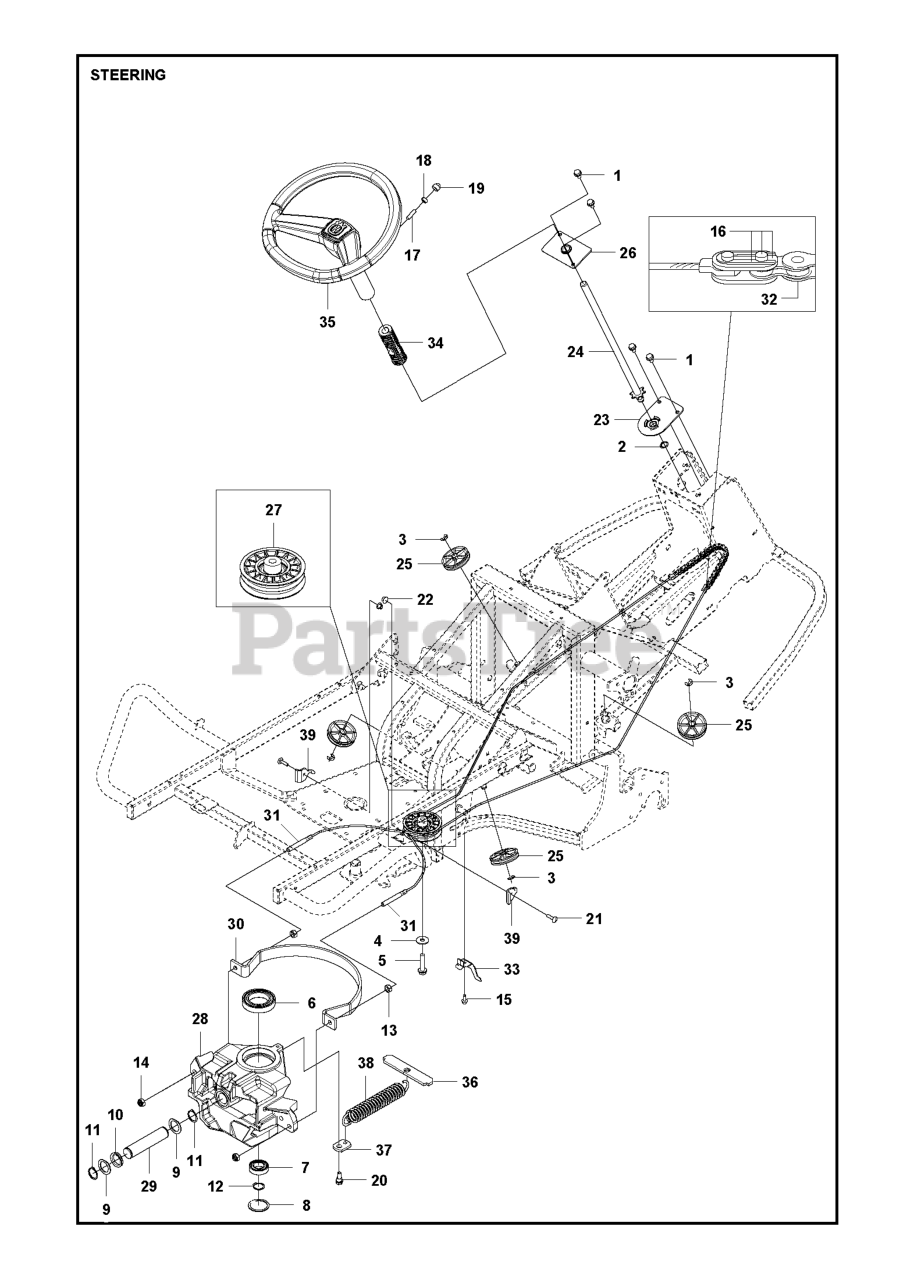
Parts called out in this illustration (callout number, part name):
2	RETAINING RING SGA 15
3	RETAINING RING
5	COLLAR SCREW
6	BALL BEARING 6010 2RS1
7	Ball Bearing 6005-2rs
8	CIRCLIP SGH 47
11	Retaining Ring
12	RETAINING RING SGA 25
13	NUT
14	NUT
18	NUT
19	PROTECTIVE COVER
22	NUT FLANGE
24	STEERING ROD ASSY LONG
26	BRACKET STEERING ASSY WITH BUS
34	DRIVER STEERING WHEEL
35	STEERING WHEEL
